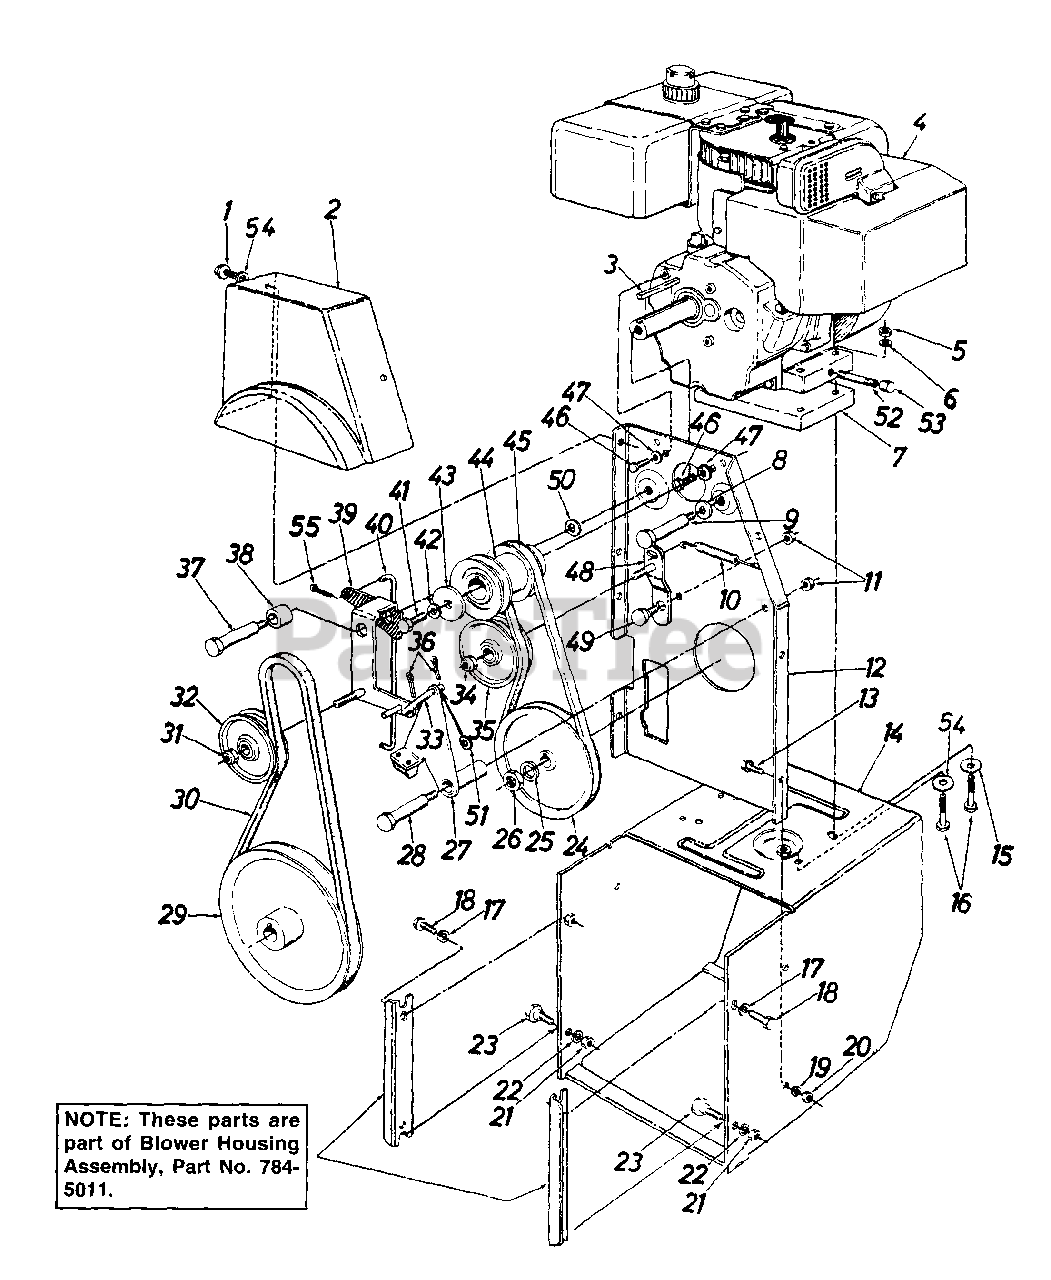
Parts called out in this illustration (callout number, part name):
1	Hex AB-Tap Scr. 5/16 x .75" Lg.
2	Belt Cover
3	Sq. Key 1/4" x 1.50" Lg.
4	Engine
5	Hex Nut 5/16-18 Thd.
6	L-Wash. 5/16" I.D.
7	Engine Spacer Ass'y.
8	Bell-Wash .40 I.D. x .88 O.D.
9	Shld. Bolt .498" Dia. x 3.00" Lg.
10	Ext. Spring .38 O.D. x 3.18" Lg.
11	Hex Cent. L-Nut 3/8-16 Thd.
12	Engine Brkt. Ass'y.
13	Hex Sems Scr. 5/16-18 x .75" Lg.
14	Frame Ass'y.
15	Fl-Wash .344" I.D. x 1.125" O.D. x .12"
16	Hex Bolt 5/16-18 x 2.25" Lg.
17	L-Wash. 3/8" I.D. H.D.
18	Pilot Scr. 3/8-16 x .88" Lg.
19	L-Wash. 5/16" I.D.
20	Hex Nut 5/16-18 Thd.
21	Hex Nut 3/8-16 Thd.
22	L-Wash. 3/8" I.D. H.D.
23	Shld. Bolt .498" Dia. x .340" Lg.
24	V-Pulley .628 I.D. x 7.50 O.D,
25	L-Wash. for 5/8" I.D.
26	Hex Ins. Jam L-Nut 5/8-18 Thd.
27	Brake Brkt. Ass'y.
28	Shld. Bolt .498" Dia. x 2.00" Lg.
29	"V"-Pulley .875 I.D. x 10.12 O.D.
30	"V"-Belt
31	Hex Ins Jam L-Nut 3/8-24 Thd.
32	Fl-Idler w/Flanges 3.0 O.D
33	Brake Linkage Ass'y.
34	Hex Ins. Jam L-Nut 3/8-24 Thd.
35	3.0" O.D. Fl-Idler w/Flanges
36	Int. Cot Pin 3/32" Dia.
37	Shld. Bolt .625" Dia. x 2.750" Lg.
38	Spacer 75 O.D. x 1.00" Lg
41	Hex Bolt 3/8-24 x 1.25" Lg.
42	L-Wash 3/8" I.D H.D.
43	Fl-Wash.
44	Engine Pulley - Double Groove
45	"V"-Belt
46	Hex Bolt 5/16-24 x .62" Lg.
47	Bell-Wash .345 I D. x .88 O.D. x 060
48	Drive Idler Brkt. Ass'y
49	Shld. Bolt - 625" Dia. x .170" Lg.
50	Bell-Wash 40 I D x 1.12 O.D.
51	Fl-Wash 385" I D. x .620" O.D.
52	Pipe Nipple - 1/4" Pipe Thd x 3.5" Lg.
53	Hex Hd. Cap 1/4-18 Pipe Thd.
54	Fl-Wash,344" I D. x .62" O.D. x .63"
55	Int. Cot. Pin 5/16" Dia.
